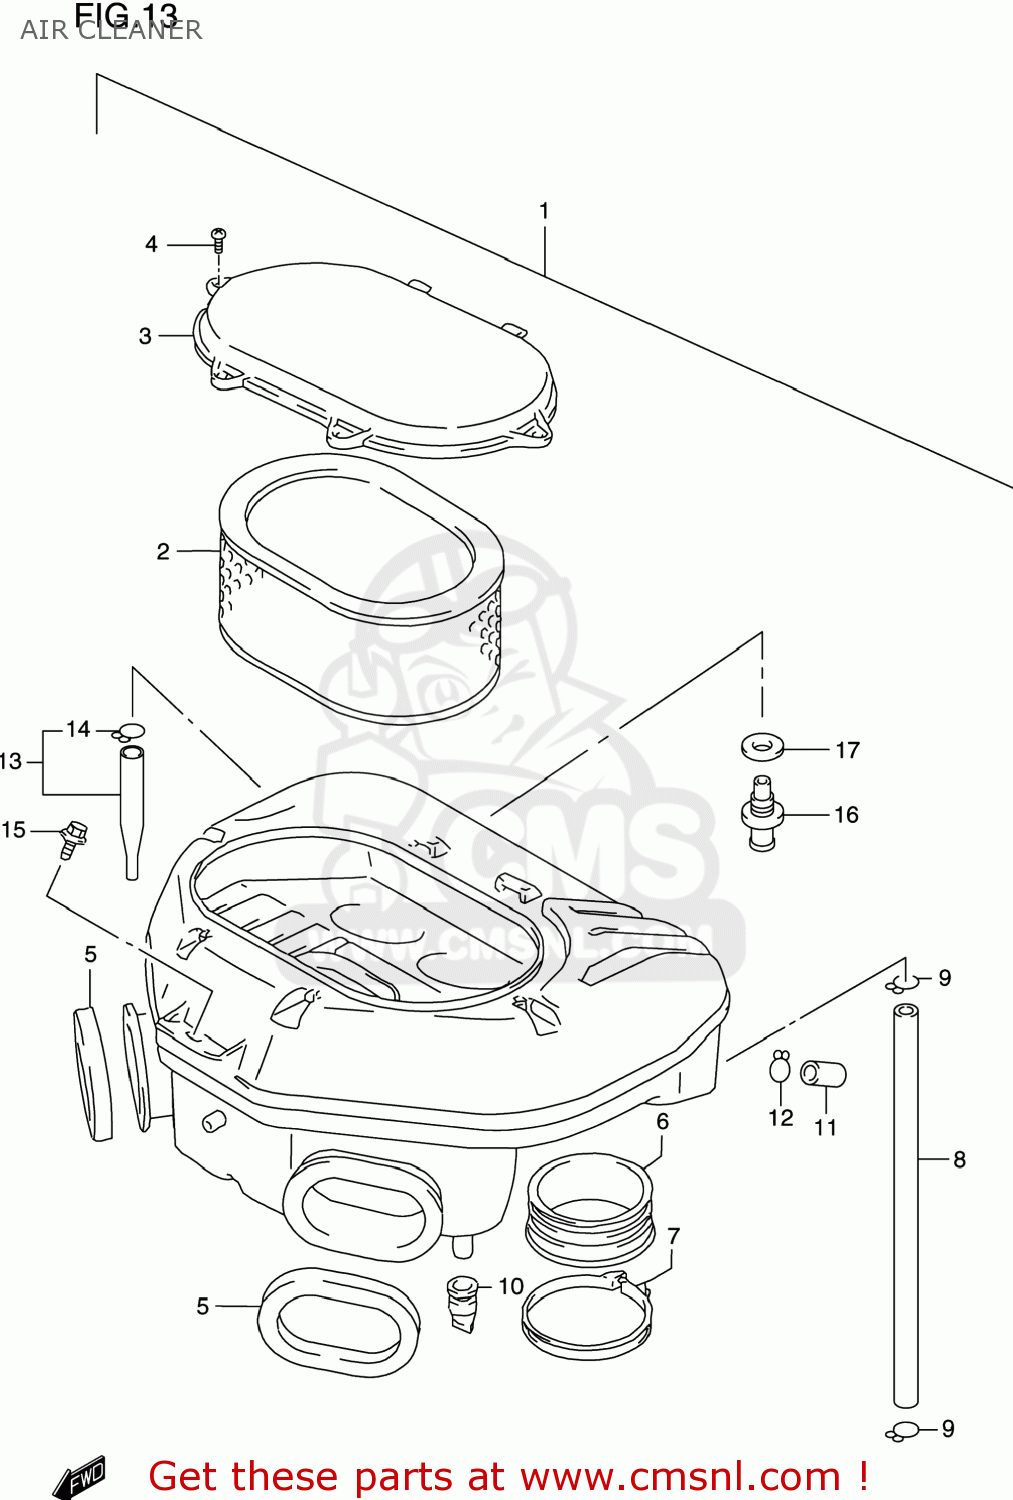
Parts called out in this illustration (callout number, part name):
1	CLEANER ASSY,AIR
2	FILTER,AIR CLEANER
3	CAP,AIR CLEANER
4	SCREW 5X12
5	CUSHION,DUCT
6	TUBE,OUTLET
7	CLAMP
8	TUBE,BREATHER
9	CLIP
10	CAP,DRAIN
11	PLUG
12	CLIP
13	TUBE,CONTROLL AIR
14	CLIP
15	BOLT
16	UNION,2ND AIR
17	GASKET(12.2X21X0.8) (NAS)
